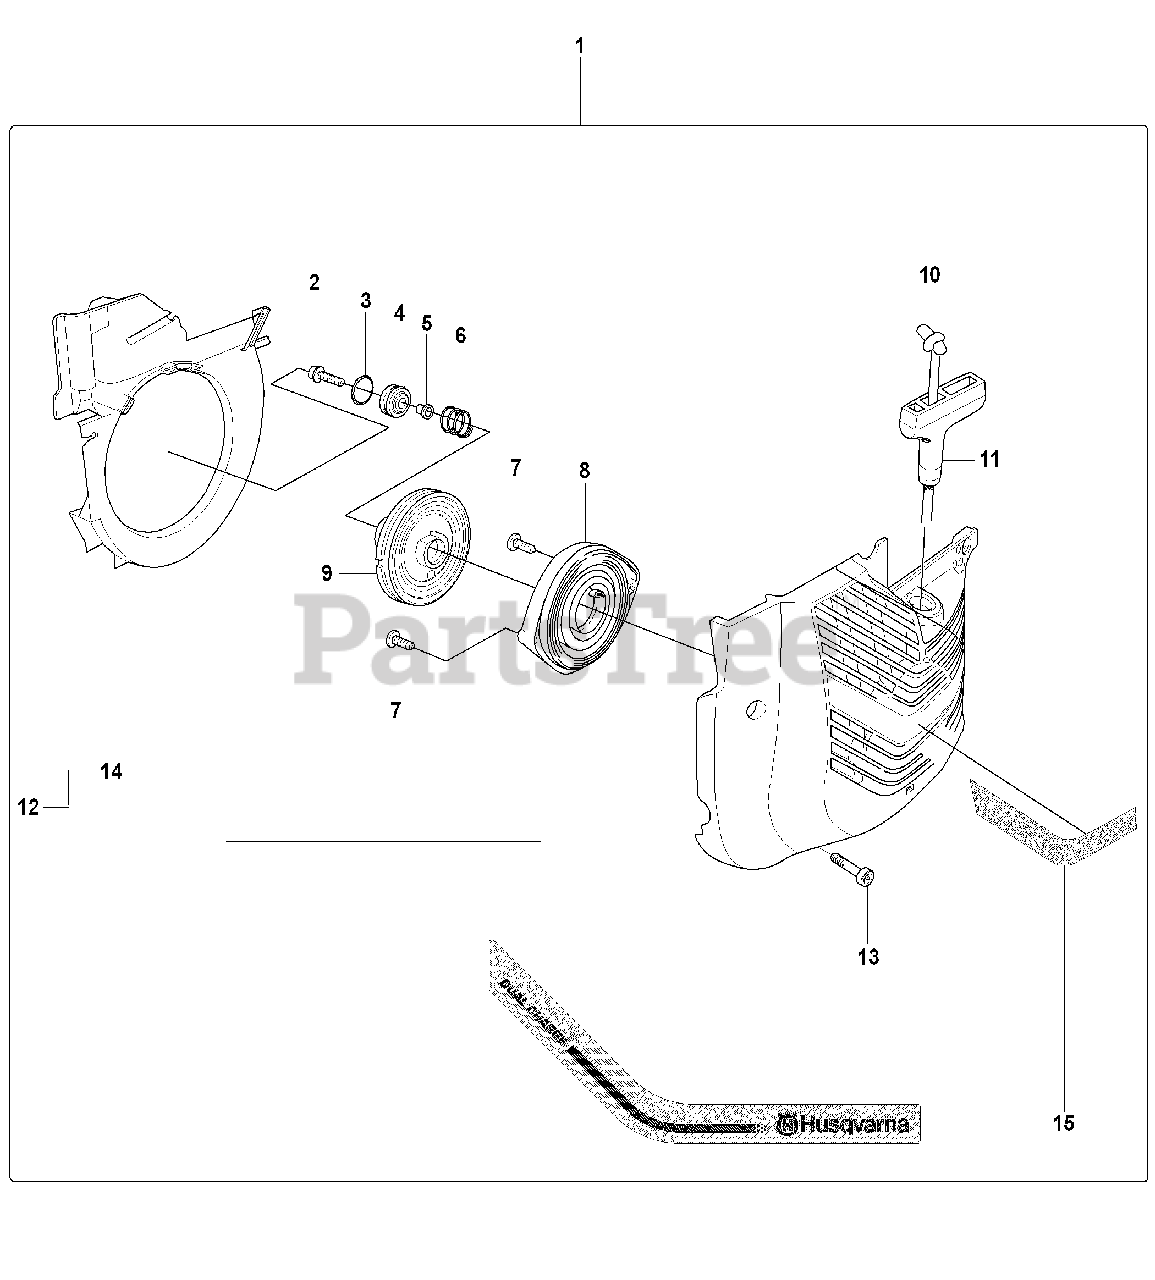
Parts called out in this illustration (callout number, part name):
1	STARTER
2	SCREW
4	GROMMET
5	SPACING SLEEVE
6	COMPRESSION SPRING
8	RECOIL SPRING
9	STARTER PULLEY
10	STARTER CORD
11	STARTER HANDLE
12	STARTER COVER
14	COOLING AIR CONDUCTOR
